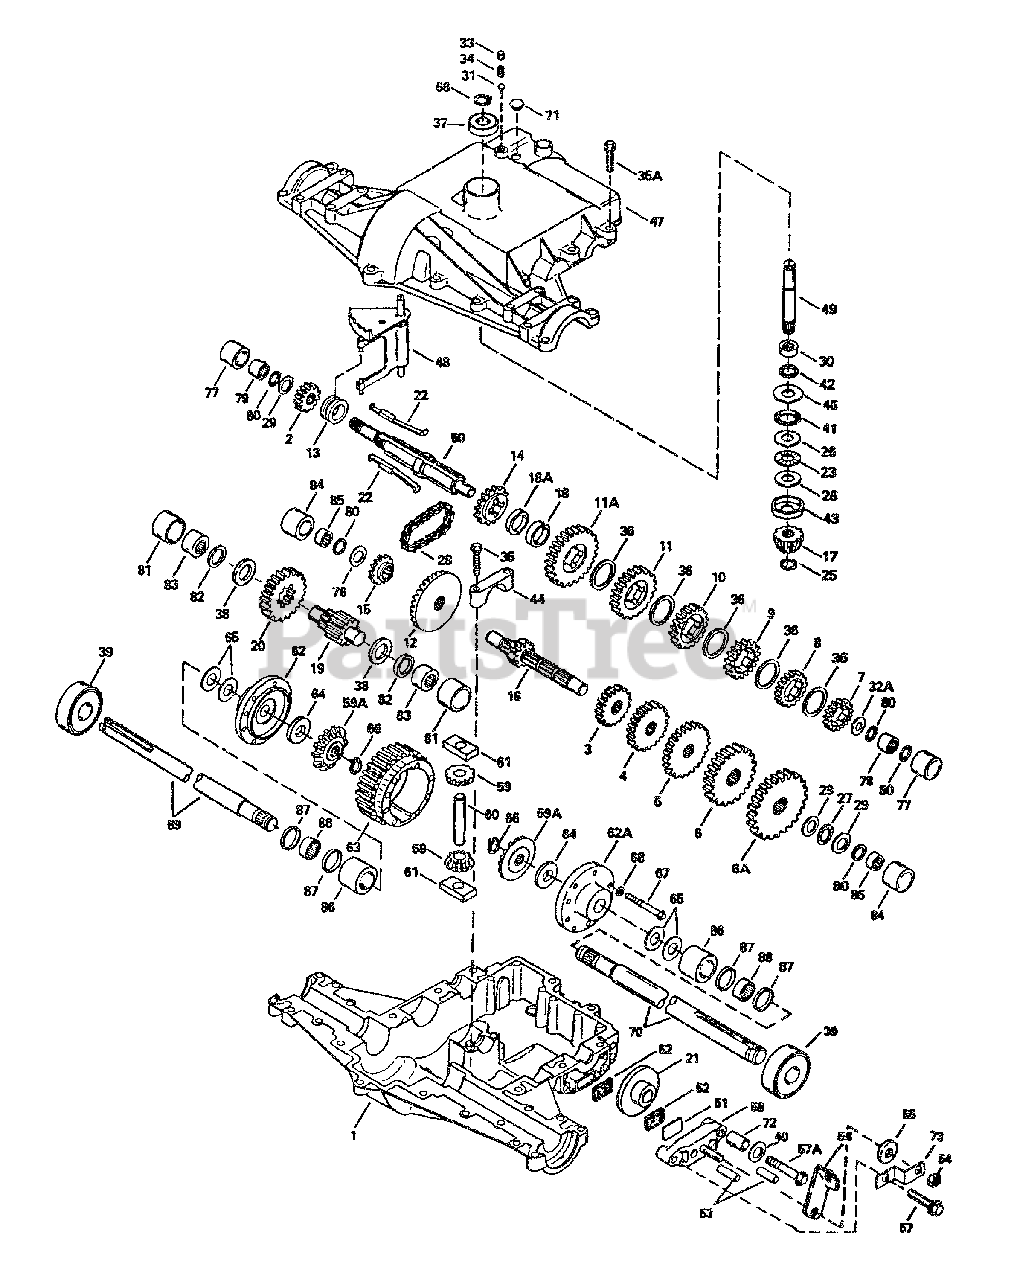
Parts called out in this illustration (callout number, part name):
1	Case, Transaxle
2	Gear, Spur ( 15 teeth)
3	Gear, Spur (12 teeth)
4	Gear, Spur (18 teeth)
5	Gear, Spur (25 teeth)
6	Gear, Spur (28 teeth)
6A	Gear, Spur (31 teeth)
7	Gear, Spur (19 teeth)
8	Gear, Spur (22 teeth)
9	Gear, Spur (25 teeth)
10	Gear, Spur (32 teeth)
11	Gear, Spur (37 teeth)
11A	Gear, Spur (41 teeth)
12	Gear, Bevel (33 teeth)
13	Collar, Shift
14	Sprocket (18 teeth)
15	Sprocket (9 teeth)
16	Shaft, Counter (w/9 tooth gear)
17	Bevel Pinion, Input (13 teeth)
18	Spacer, Neutral (.350/.340 thick)
18A	Spacer, Neutral (.276/.268 thick)
19	Shaft, Output (9 teeth)
20	Gear, Output (35 teeth)
21	Disk, Brake
23	Bearing, Thrust
25	Ring, Retaining
26	Washer, Thrust
27	Bearing, Thrust
28	Chain, Roller (No. 41 chain, 24 links)
29	Washer, Thrust
30	Bearing, Needle
31	Ball, Steel
32A	Washer, Thrust
33	Screw, Set, 3/8-16 x 3/8
35	Screw, Flanged hex hd thread forming, 1/4-20 x 1-1/4
35A	Screw, Hex hd. thread forming, 5/16-18 x 1-1/4
36	Washer, Thrust
37	Bearing, Ball
38	Washer, Thrust
39	Bearing, Ball
40	Washer, Flat
41	"O" Ring
42	Seal, Oil
43	Washer, Cupped
44	Cap, Bearing
45	Washer, Flat
47	Cover, Transaxle
48	Rod & Fork Assy., Shift
49	Shaft, Input
50	Shaft, Brake (4 Keyed)
51	Plate, Brake pad
52	Pad, Brake
53	Pin, Dowel
54	Locknut, 5/16-24
55	Washer, Flat
56	Lever, Brake
57	Screw, Flanged hex hd. thread forming, 1/4-20 x 1-1/4
57A	Screw, Flanged hex hd. thread forming, 1/4-20 x 2-1/4
58	Holder, Brake pad
59	Pinion, Differential bevel
59A	Gear, Bevel
60	Pin, Drive
61	Block, Drive
62	Carrier, Differential (Threaded holes)
62A	Carrier, Differential
63	Gear, Ring (31 teeth)
65	Washer, Thrust
66	Ring, Snap
67	Screw, Hex hd., 1/4-20 x 2-1/4
68	Lockwasher, 1/4"
69	Axle (12-5/16" long)
70	Axle (16-3/16" long)
71	Plug, Hex hd., 9/16-18 thread
73	Bracket, Brake lever
77	Sleeve (stepped)
78	Bearing, Needle
79	Bearing, Needle (capped)
80	"O" Ring
81	Sleeve (stepped)
82	Ring, Square cut
83	Bearing, Needle (capped)
84	Sleeve (stepped)
85	Bearing, Needle (capped)
86	Sleeve (stepped)
87	Ring, Square cut
88	Bearing, Needle
